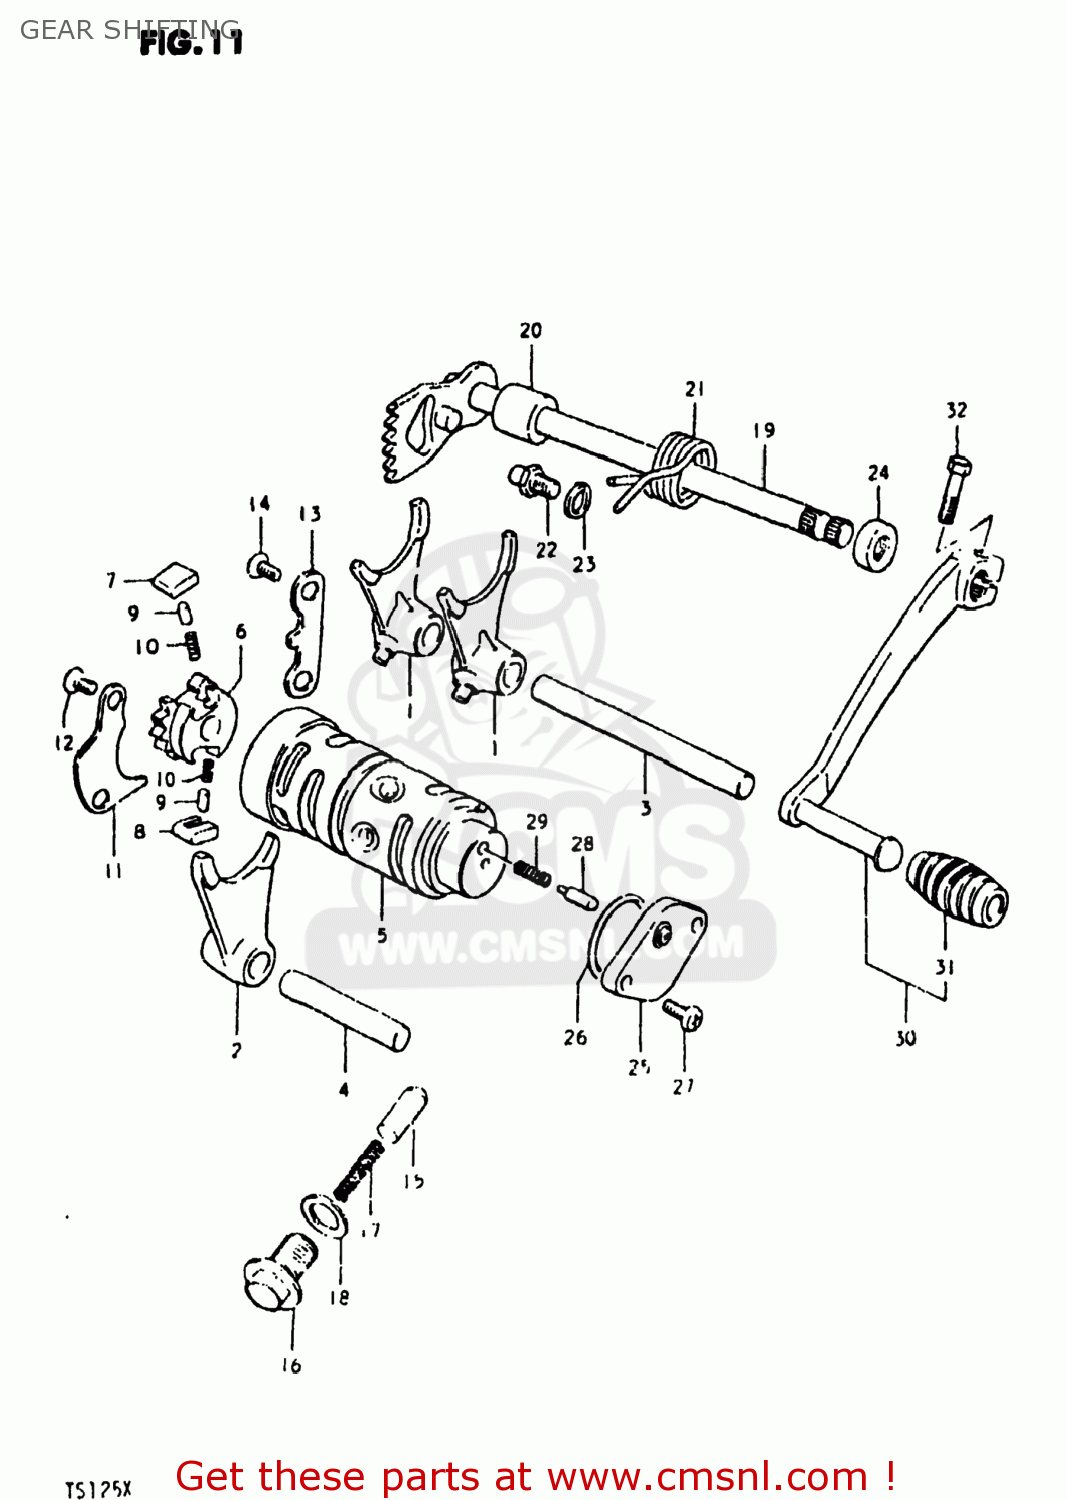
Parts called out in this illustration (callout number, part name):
1	FORK,GEAR SHIFT NO.1
2	FORK,GEAR SHIFT NO.2
3	SHAFT,GEAR SHIFT FORK
4	SHAFT,GEAR SHIFT FORK
5	CAM,GEAR SHIFT
6	RETAINER,GEAR SHIFT CAM
7	PAWL,GEAR SHIFT NO.1
8	PAWL,GEAR SHIFT NO.2
9	PIN(5X8)
10	SPRING
11	LIFTER,GEAR SHIFT PAWL
12	SCREW
13	GUIDE,GEAR SHIFTING CABLE
14	SCREW
15	STOPPER,GEAR SHIFTING
16	BOLT,GEAR SHAFT CAM STOPPER
17	SPRING
18	GASKET(14X19.2X2) (NAS)
19	SHAFT,GEAR SHIFT
20	SPACER(12X20X15.3)
21	SPRING
22	STOPPER,GEAR SHIFT CAM
23	WASHER
24	OIL SEAL
25	BODY,GEAR SHIFT SWITCH
26	O-RING (D:2.4 ID:26.2)
27	SCREW
28	PIN(5X15.5)
29	SPRING
30	LEVER ASSY,GEAR SHIFT
31	RUBBER,GEAR SHIFT PEDAL
32	BOLT
